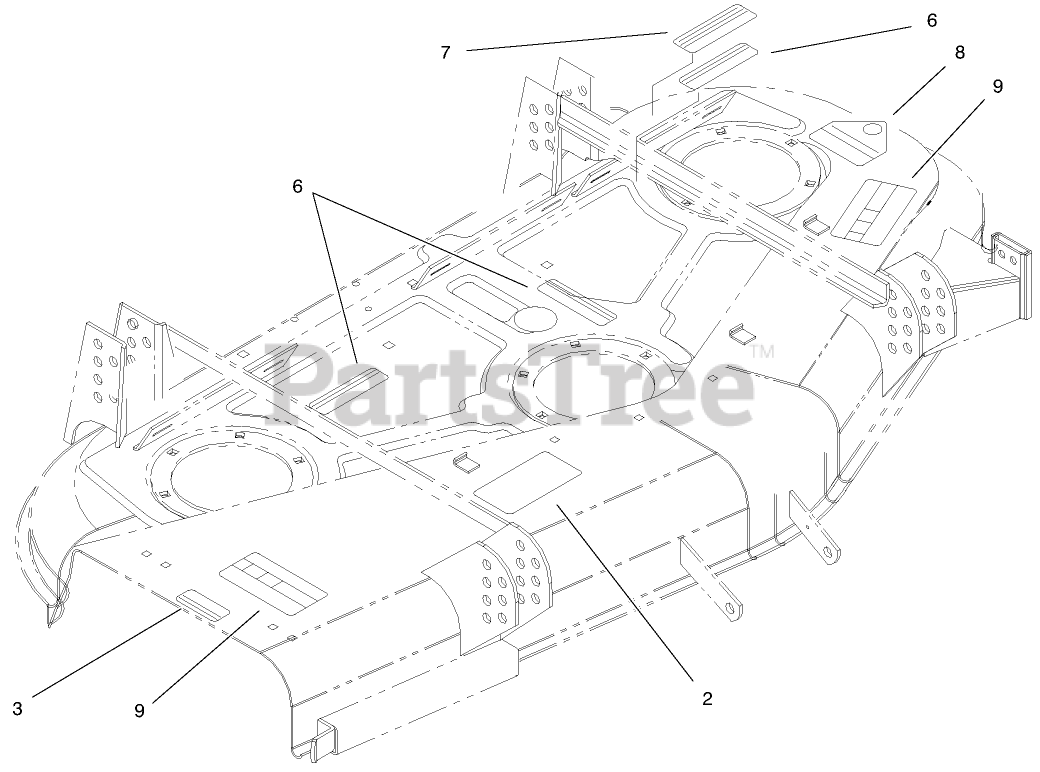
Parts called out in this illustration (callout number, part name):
2	DECAL-WARNING
3	DECAL-DANGER
6	DECAL-DANGER
7	DECAL-TORQUE
8	DECAL-DANGER
9	DECAL-DANGER, THROWN OBJECT
